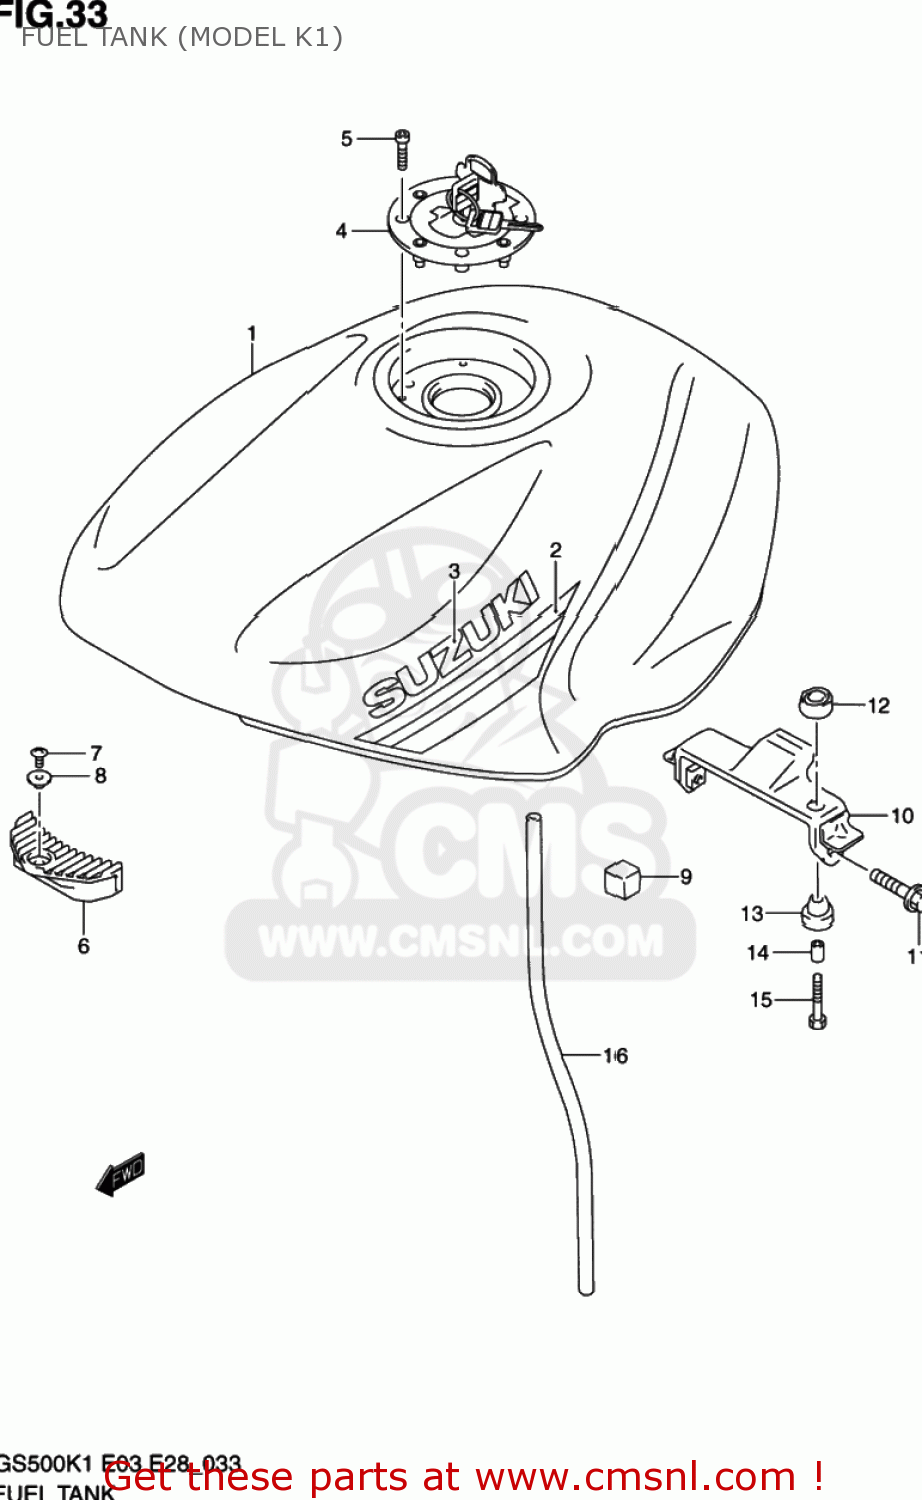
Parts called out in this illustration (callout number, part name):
1	TANK ASSY,FUEL(BLUE)
2	TAPE SET,FUEL TANK
3	EMBLEM,FUEL TANK
4	CAP SET,FUEL TANK
5	BOLT(5X20)
6	CUSHION,FUEL TANK FR
7	SCREW
8	WASHER
9	CUSHION,FUEL TANK SIDE
10	BRACKET,FUEL TANK RR
11	BOLT
12	CUSHION
13	CUSHION
14	SPACER(6.5X9X18)
15	BOLT(6X30)
16	HOSE,WATER DRAIN
